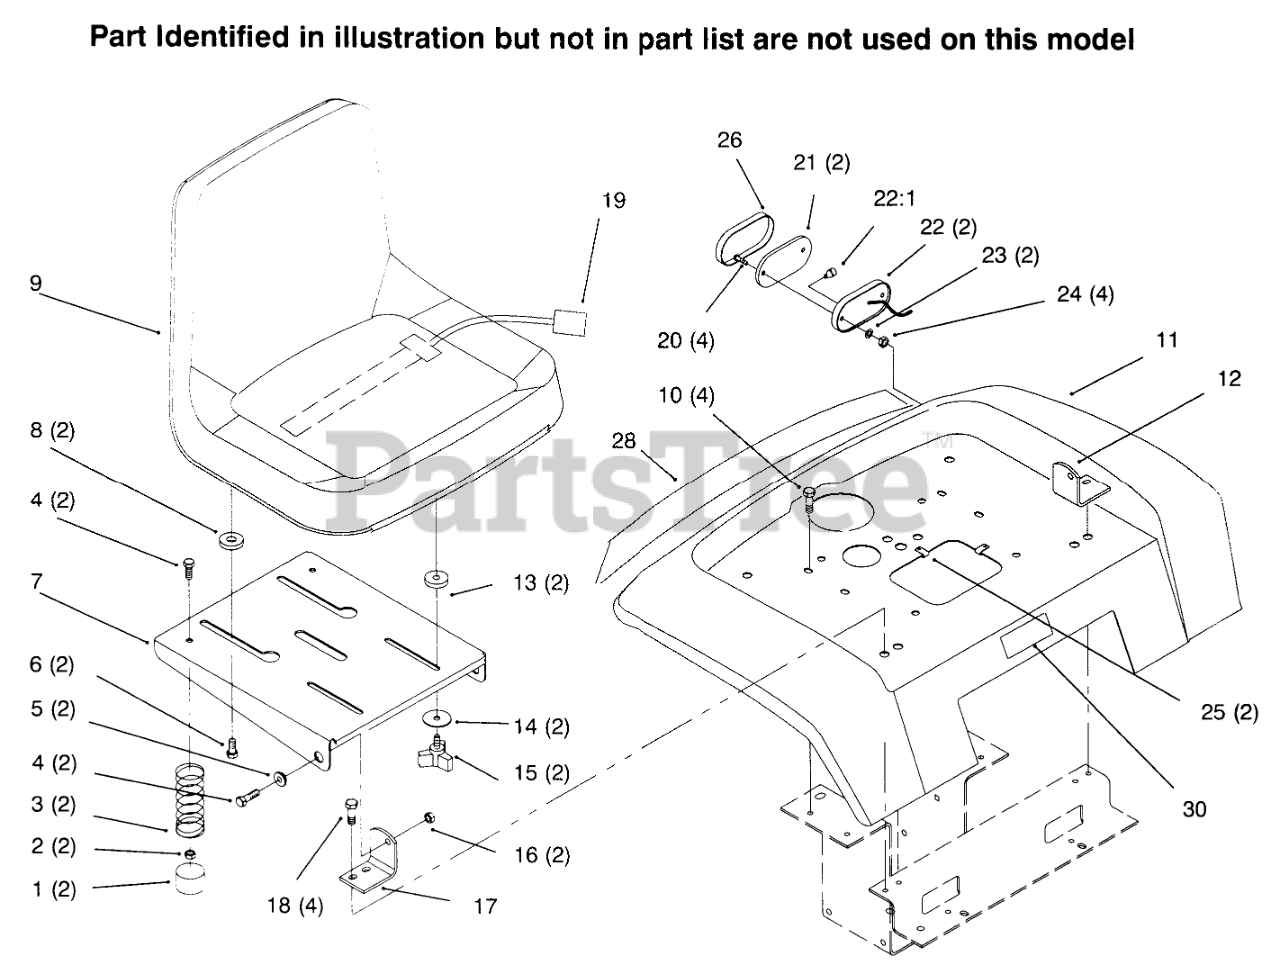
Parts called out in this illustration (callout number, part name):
1	CAP-PROTECTOR
2	NUT-LOCK, NI
3	SPRING-COMPRESSION
4	SCREW-HH
5	BUSHING
6	BOLT-SHOULDER
7	SUPPORT - SEAT (BLACK)
8	SPACER-NYLON
9	SEAT-V-511
10	Bolt
12	BRACKET-PIVOT, LH
13	SPACER-NYLON
14	WASHER
16	NUT-LOCK, NI
17	BRACKET-PIVOT, RH
18	SCREW-HWHTF
19	SWITCH-SEAT
20	SCREW-PPH
22	BASE-TAIL LIGHT
23	WASHER-LOCK, INT
24	NUT-LOCK, NI
25	SPEED CLIP
26	LENS-TAIL LIGHT
28	Decal-Rear Fender
30	DECAL - WHEELHORSE
